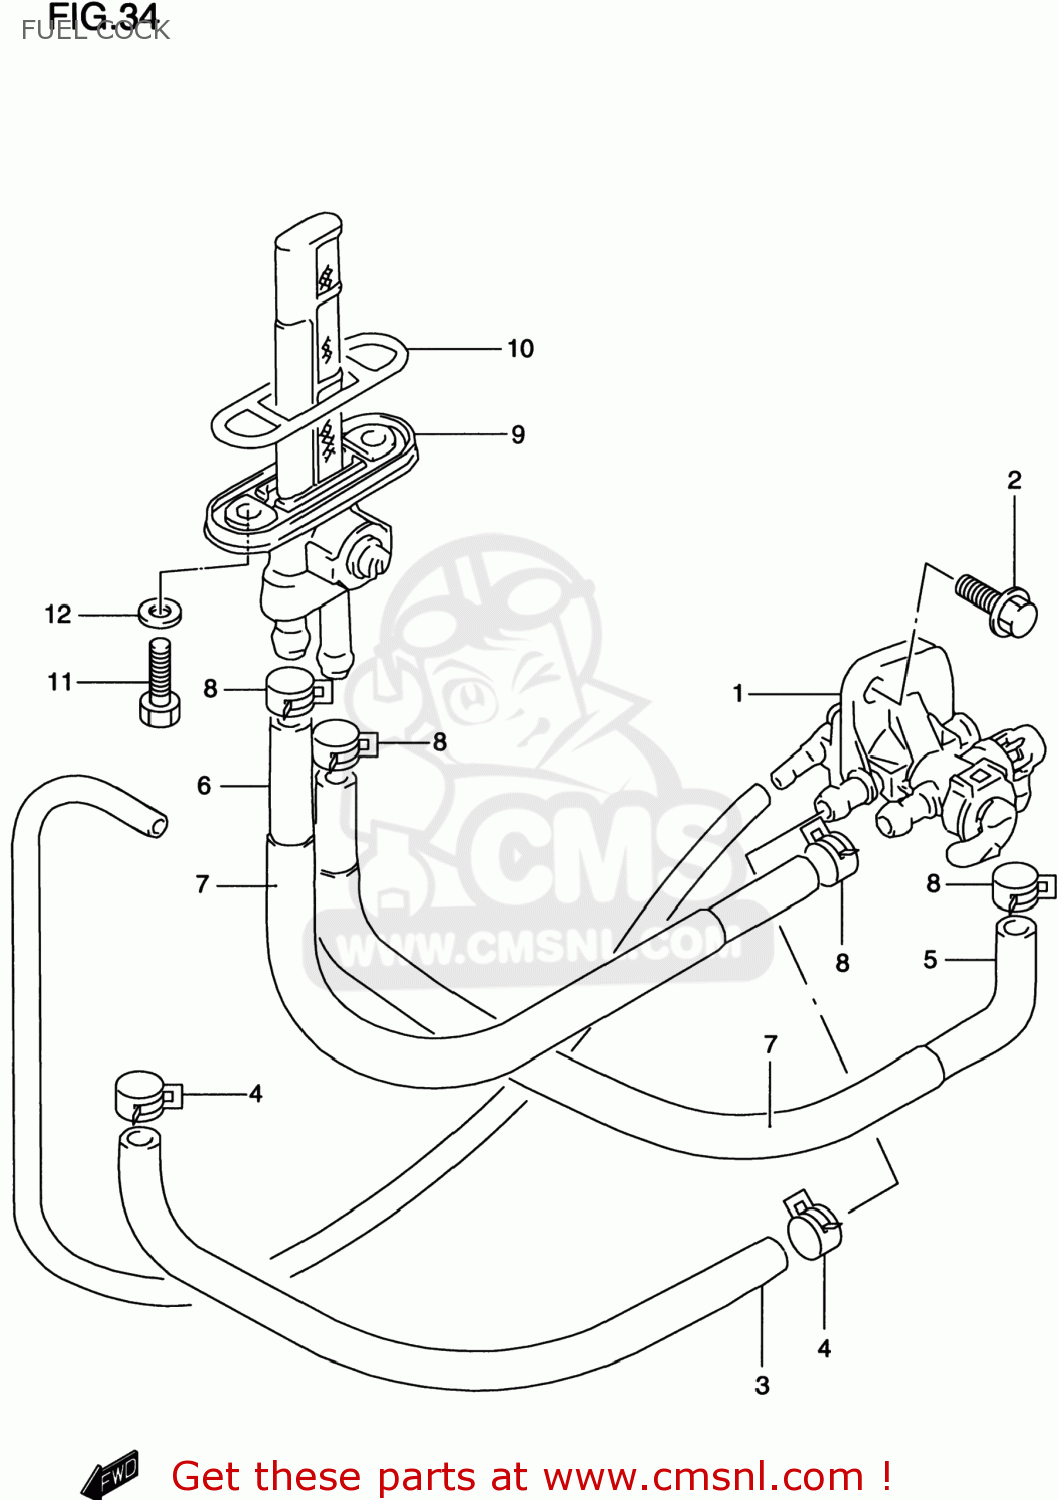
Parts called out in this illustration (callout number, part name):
1	COCK ASSY,FUEL
2	BOLT
3	HOSE
4	CLIP
5	HOSE
6	HOSE,FUEL RESERVE
7	PROTECTOR,FUEL HOSE
8	CLIP
9	COCK ASSY,FUEL NO.1
10	O RING,FUEL COCK
11	BOLT(6X20)
12	GASKET(6.4X11.5X0.8) (NAS)
